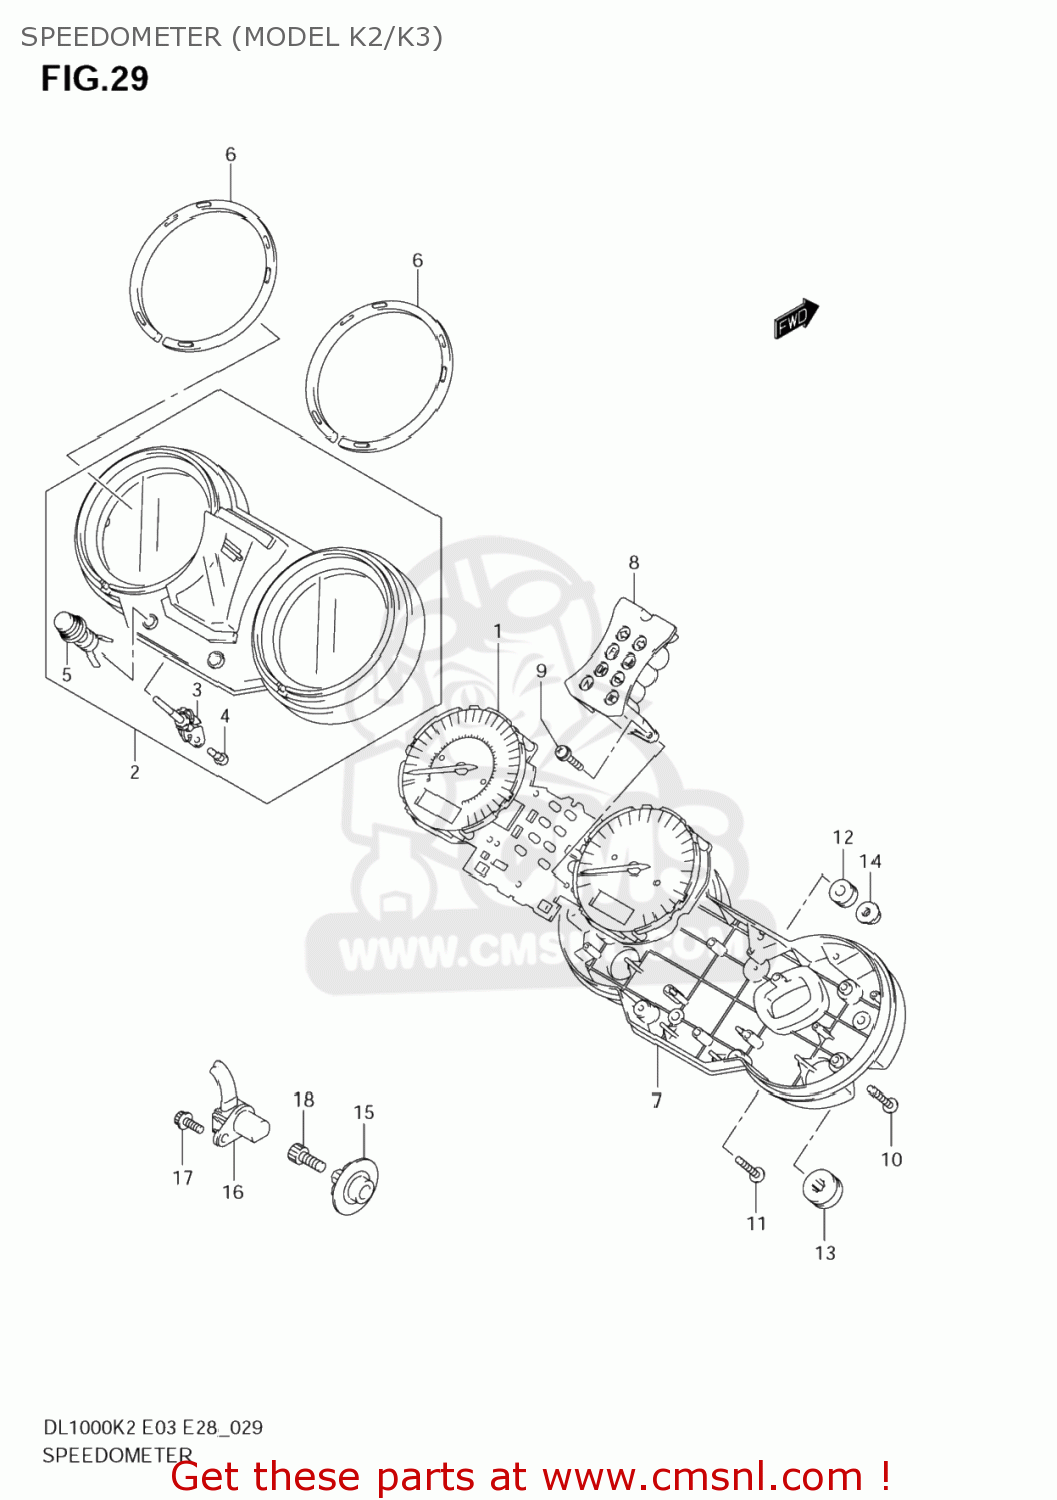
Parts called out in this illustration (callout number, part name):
1	SPEEDOMETER
2	UPR CASE
3	SWITCH LEVER
4	SCREW(3X10)
5	GUM,SWITCH
6	DAMPER
7	LWR CASE
8	INNER CASE
9	SCREW,PAN HEAD(3X14)
10	SCREW(3X16)
11	SCREW,PAN HEAD(3X16)
12	CUSHION
13	CUSHION
14	NUT
15	ROTOR,SPEED
16	SENSOR,SPEED
17	BOLT
18	BOLT
